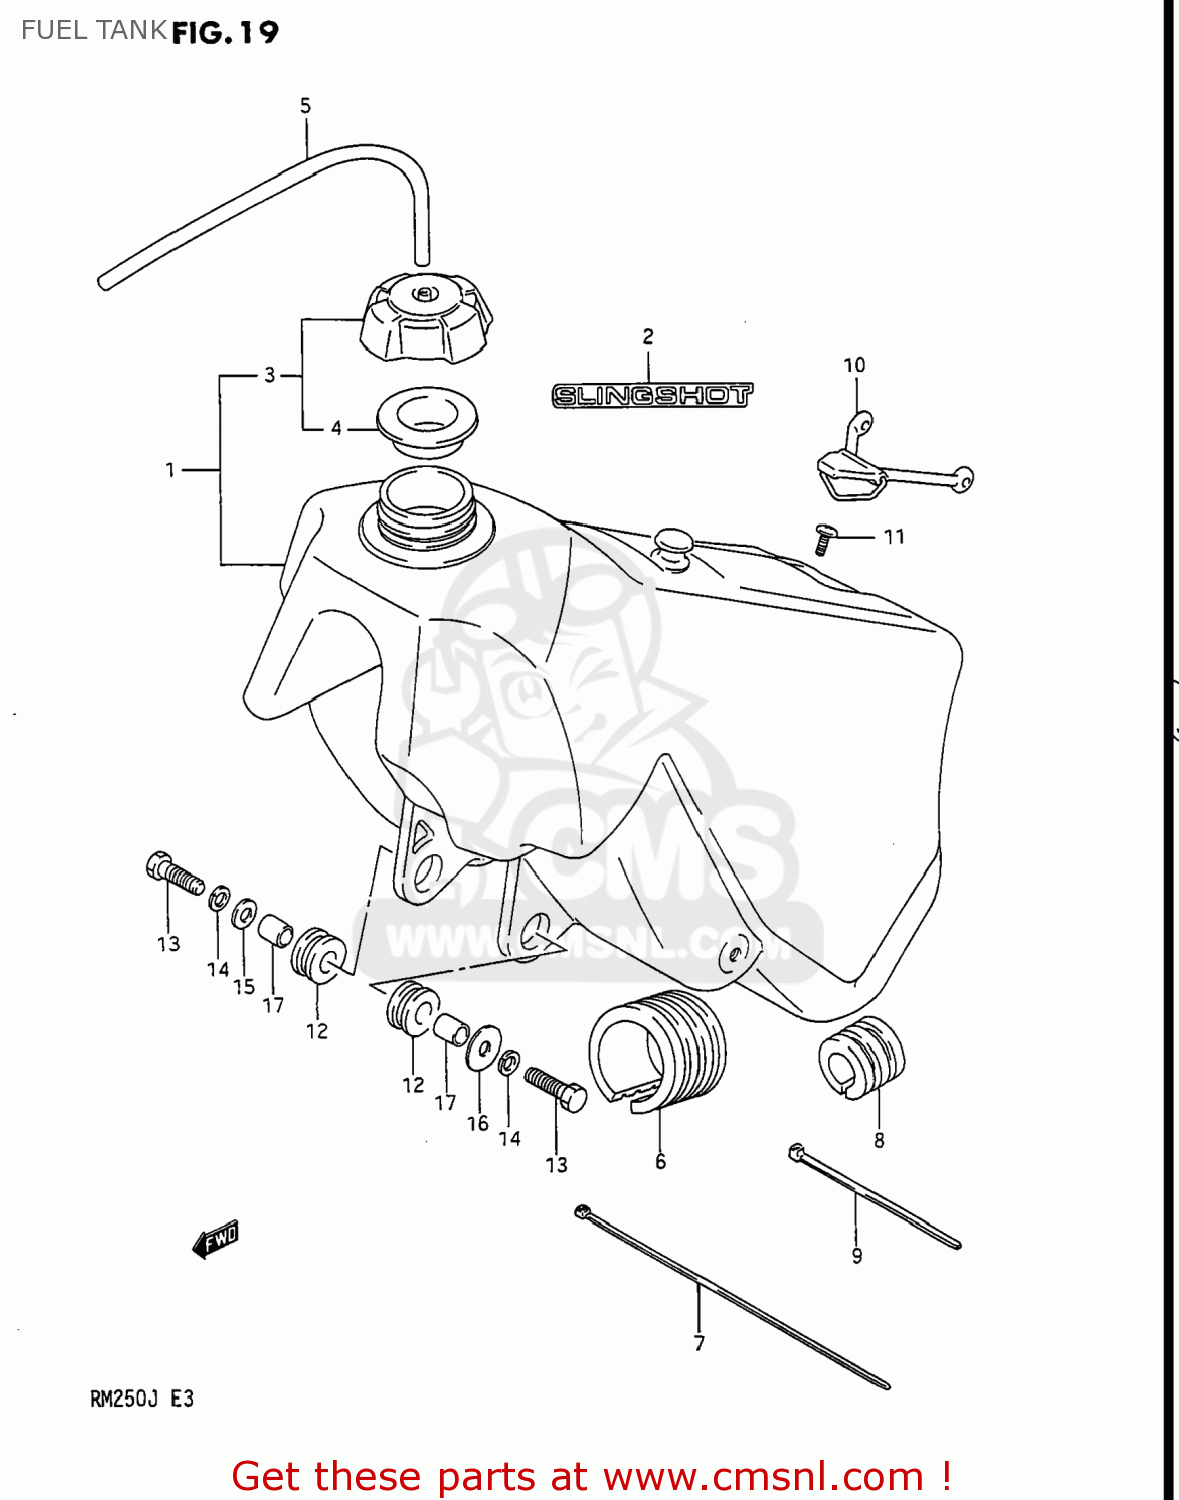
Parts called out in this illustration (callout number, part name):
1	TANK SET,FUEL
2	EMBLEM
3	CAP SET,FUEL TANK
4	GASKET,FUEL TANK CAP (NAS)
5	HOSE
6	CUSHION,FUEL TANK NO.1
7	CLAMP
8	CUSHION,FUEL TANK NO.2
9	CLAMP(L:145)
10	BAND,FUEL TANK RR
11	SCREW
12	CUSHION
13	BOLT
14	LOCK WASHER
15	WASHER
16	WASHER(8.5X26X1.2)
17	SPACER(8.4X12X12)
